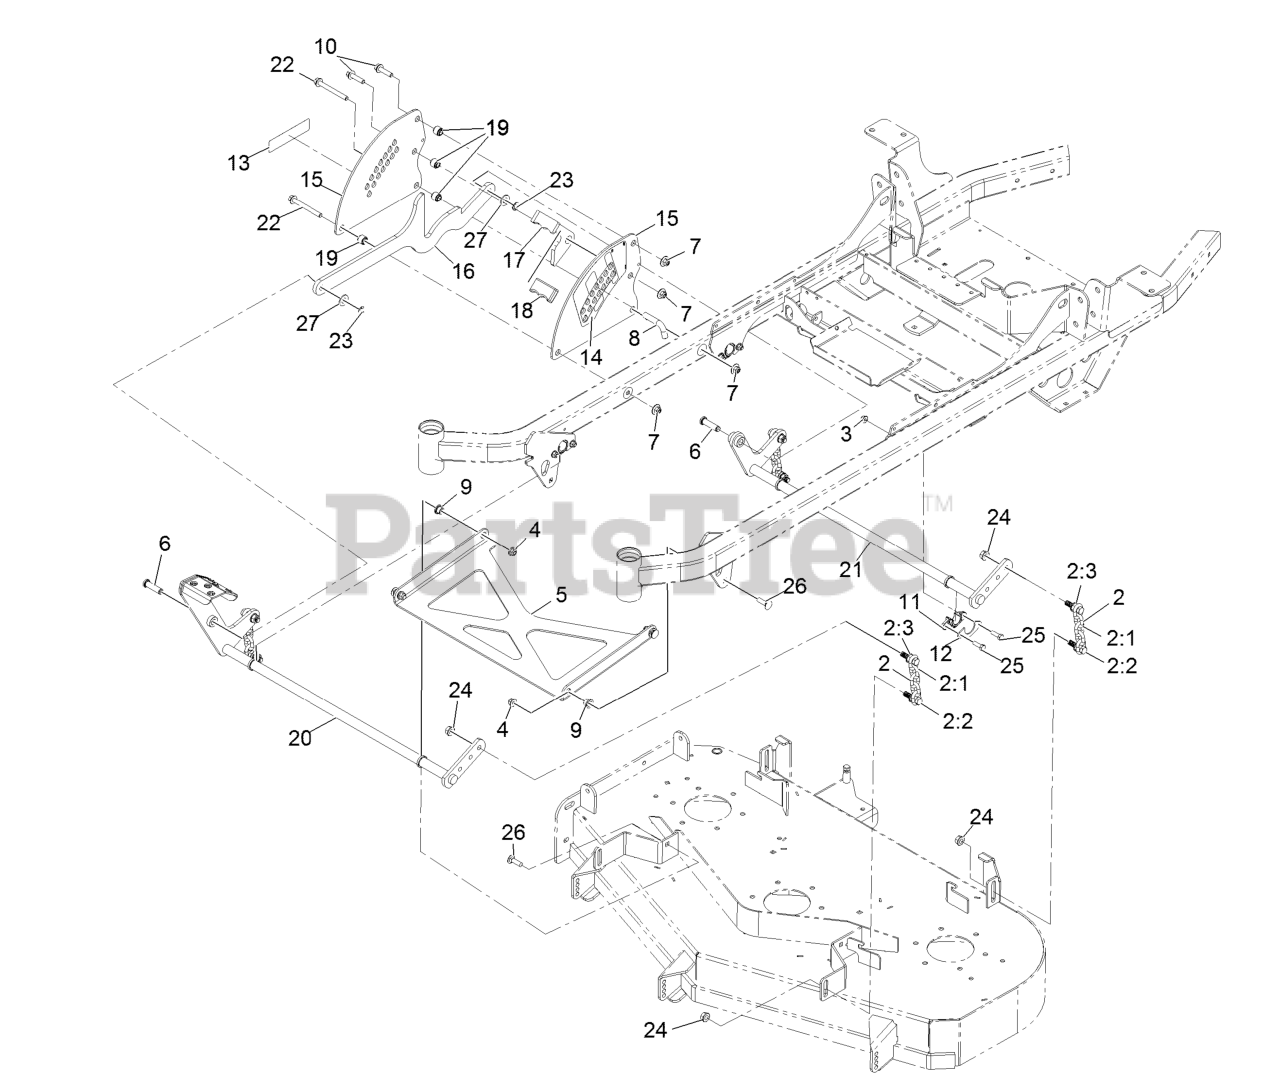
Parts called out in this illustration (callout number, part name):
2	DECK CHAIN ASM
2:1	CHAIN-LIFT, DECK
2:2	SCREW-HH
3	NUT-HF, NI
4	NUT-HF, NI
5	STRUT-DECK
6	PIN-CLEVIS
7	Nut-Nyloc 3/8-16 Flg
8	PIN-HOC
9	BUSHING-FLANGED
10	SCREW-HHF
11	BUSHING-FLANGE
12	GUSSET-LIFT, DECK
13	DECAL-S-SERIES
14	DECAL-HEIGHT OF CUT
15	PLATE,DECK LIFT
17	TRANSPORT LOCK-HOC
18	GRIP-FLAT
19	SPACER-STEP, DOUBLE
20	WLD-DECK LIFT SHAFT FRT
21	WLD-DECK LIFT SHAFT RR
22	SCREW-HHF
23	RING-RETAINING, EXTERNAL
25	SCREW-HH
26	BOLT-CARR
27	WASHER-FLAT
